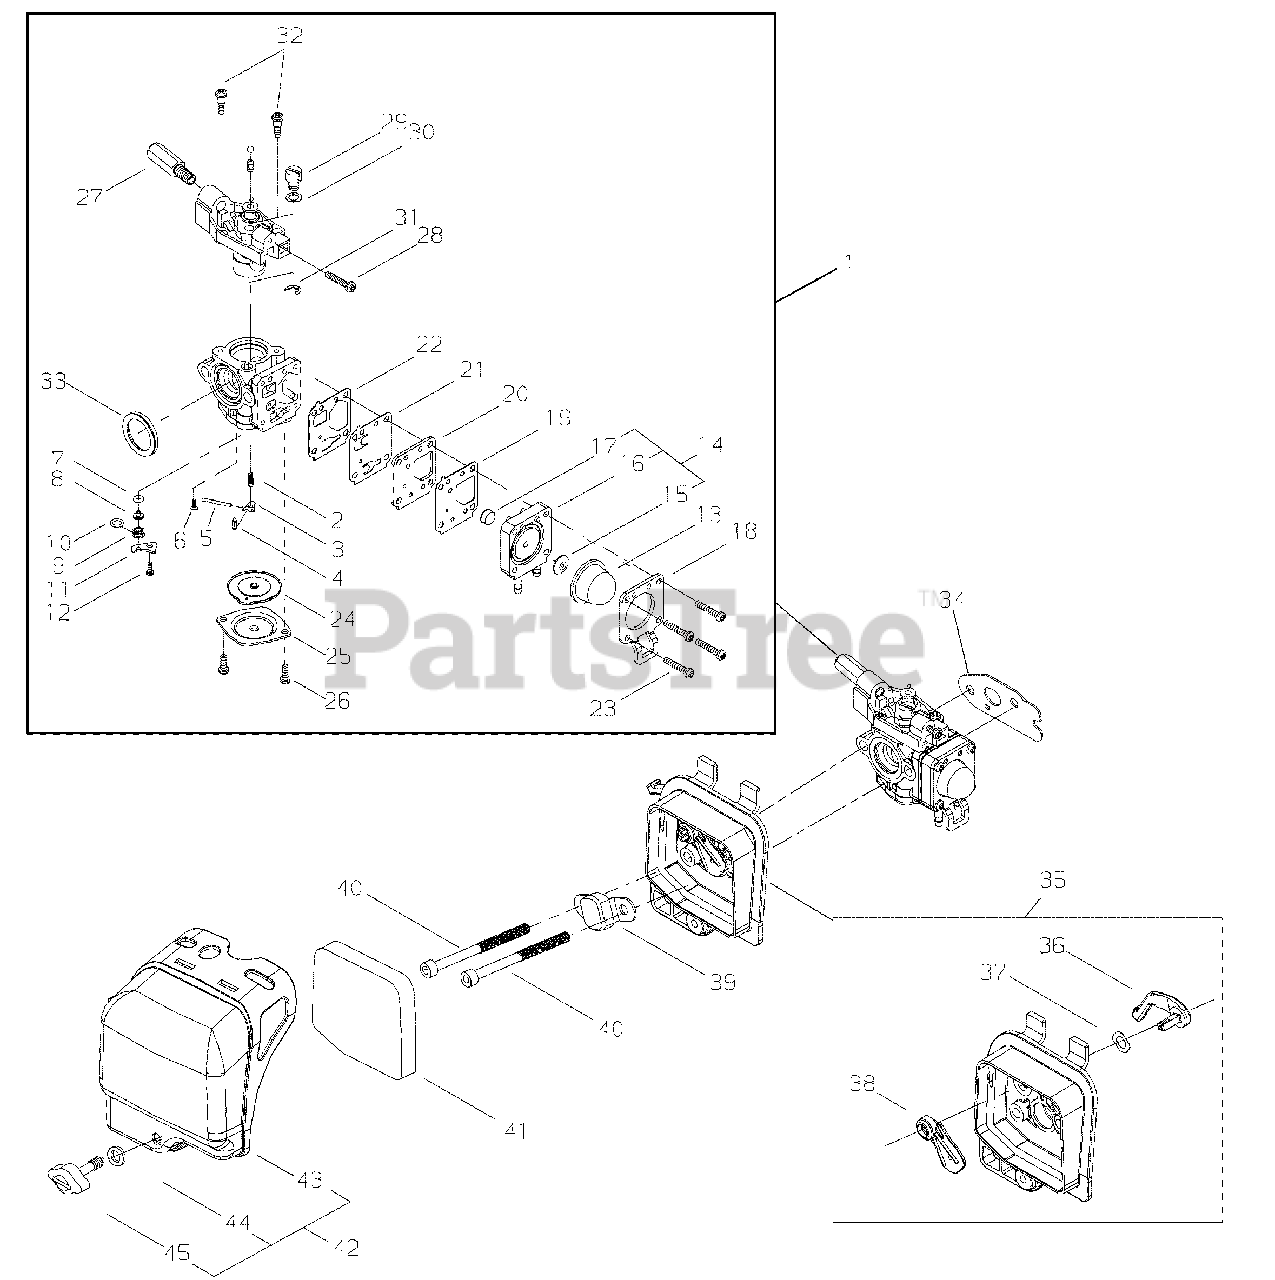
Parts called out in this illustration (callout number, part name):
1	CARBURETOR
2	SPRING, METERING LEVER
3	LEVER, METERING
4	VALVE, INLET NEEDLE
5	PIN, METERING LEVER
6	SCREW, METERING LEVER PIN
8	JET, MAIN
9	VALVE, CHECK
13	BULB, PURGE
14	BODY ASSY, PURGE
15	VALVE
16	COVER, PUMP
17	SCREEN, FUEL INLET
18	RETAINER, PURGE BULB
19	GASKET, PLATE
20	PLATE, PUMP
21	DIAPHRAGM, PUMP
22	GASKET, PUMP
23	SCREW
24	DIAPHRAGM, METERING
25	COVER, METERING DIAPHRAGM
27	ADJUSTER, THROTTLE CABLE
28	SCREW, IDLE ADJUST
33	RING, PACKING
34	GASKET, CARBURETOR
35	BASE ASSY, AIR FILTER
36	LEVER, CHOKE
37	WASHER, WAVE
38	PLATE, CHOKE
39	BRACKET
40	BOLT M5×60
41	FILTER, AIR
42	COVER ASSY, AIR FILTER
43	COVER, AIR FILTER
44	WASHER 5
45	THUMBSCREW
